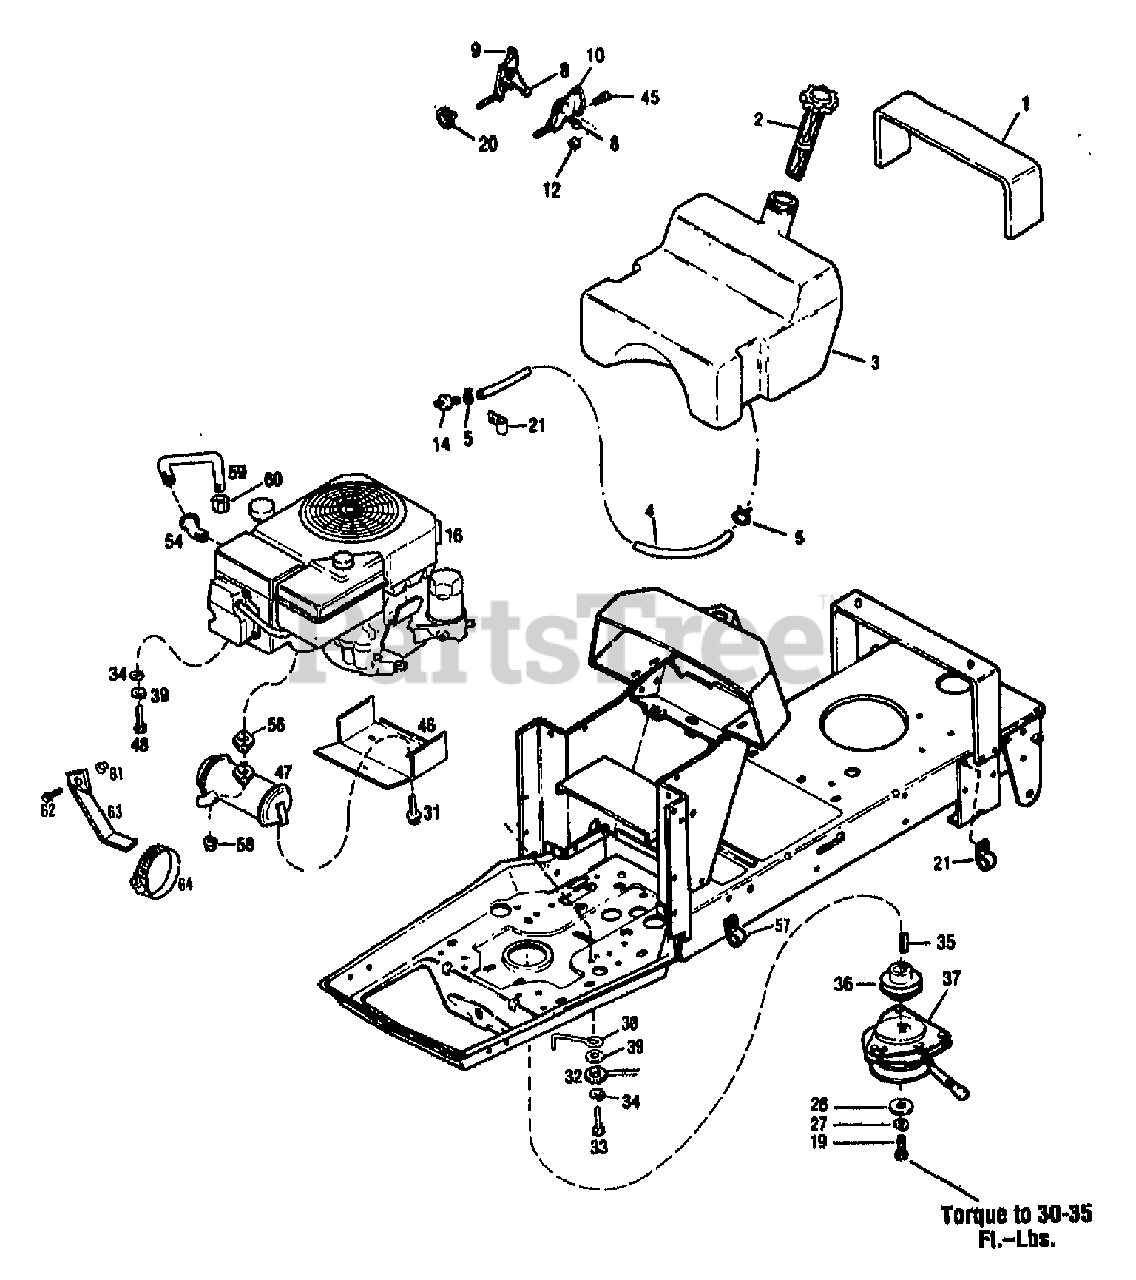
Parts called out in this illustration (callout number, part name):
1	PAD-FUEL TANK
2	CAP-GAS
3	TANK-FUEL
4	LINE-FUEL 52"
5	CLAMP-HOSE
8	KNOB
9	THROTTLE-CONTROL
10	C-CONTROL
12	NUT W/LKWASHER 10-24 ZP
14	FILTER-FUEL
16	ENGINE, KOHLER 12.5HP MODEL CV12.59(OHV)
19	SCR-HH M10X1.5X80
20	TIE-CABLE NYLON BLACK
21	CLIP-J
26	WASHER-SPEC 1.42X.468X.25 ZP
27	WASHER-LK .438 ZP
31	SCR-HFLK 1/4-20 X .375
32	HARNESS-WIRE ENGINE
33	SCR-HH M8-35
34	WASHER-LK .312 ZP
35	KEY-.25 SQ X 2.5
37	CLUTCH-ELECTRIC
38	CLUTCH-RETAINER
39	WASHER-FLAT 5/16 SAE
46	SHIELD-HEAT
47	KIT-MUFFLER
48	BOLT-M8X25
54	ELBOW-45 DEGREES
56	GASKET
57	HANGER-CABLE
58	NUT, M8X1.25
59	TUBE-OIL DRAIN
60	CAP-DRAIN TUBE
61	NUT-HF/LK 1/4-20 ZP
62	SCR-HH 1/4-20X.625
63	BRKT-MUFFLER
64	CLAMP-WORM
